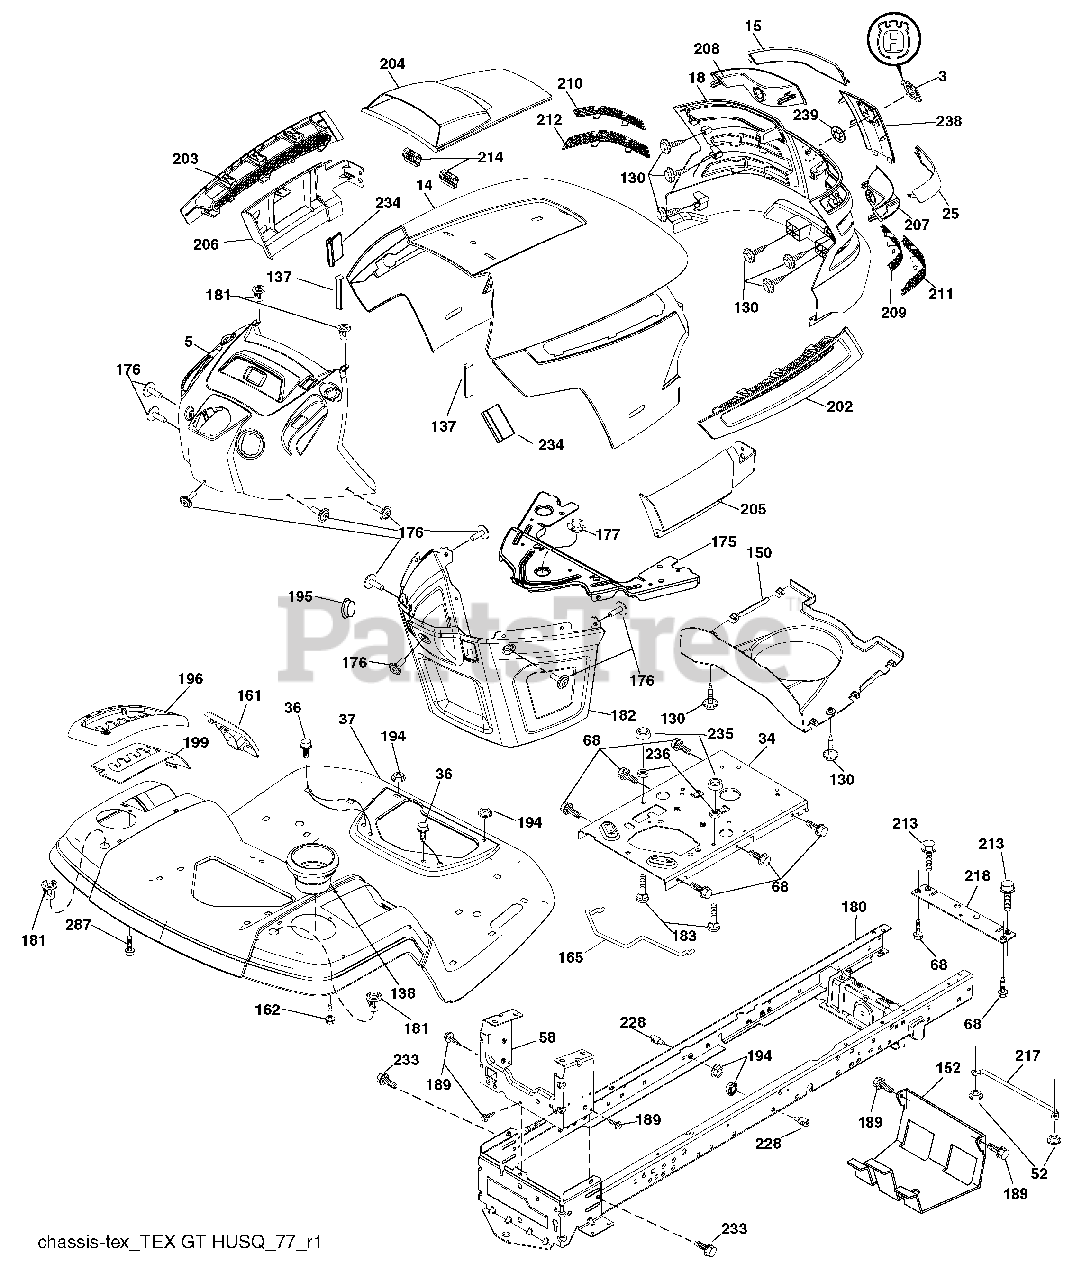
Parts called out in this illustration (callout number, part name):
3	Logo
14	Hood
34	Plate Engine
36	Screw 5/16-18 x 3/4
52	Nut Lock 5/16-18
58	Drawbar, Upper
68	Screw 5/16-18 x 1/2
130	Screw #10 x 0.750
137	Bumper Dash
138	Cupholder
150	Duct Heat Hood
152	Shield Browning/Debris
161	Console Fuel Window
162	Screw Hex Wsh Hi-Lo 1/4 x 1/2
165	Bracket Support Tank
175	Crossmember
176	Screw 10-24 x 5/8 Rnd Qdrx
177	Bushing Steering
181	Bushing Mtg. Fender Crgo.
182	Dash Lower
183	Bolt 5/16-18 x 1-1/4 Full Thd.
189	Screw 5/16-18 x 3/4
194	Nut Lock Hex Flange 5/16-18
195	Plug Hold Dash Lower
196	Console Asm. Deck Lift
199	Plate Deck Lift
202	Vent Side Hood RH
203	Vent Side Hood LH
204	Vent Asm Hood Top
205	Skirt Hood Side RH
206	Skirt Hood Side LH
209	Insert Hex Top RH
210	Insert Hex Top LH
211	Insert Hex Bottom RH
212	Insert Hex Bottom LH
213	Bolt Hex Hd 5/16-18 unc x 3/4
214	Clip Retainer
228	Stud Fastner
233	Bolt Shoulder
234	Bumper Hood
235	Spacer Fender
236	Nut Lock 5/16-18 unc
287	Screw Hex Washead 1/4-20 x 3/8
